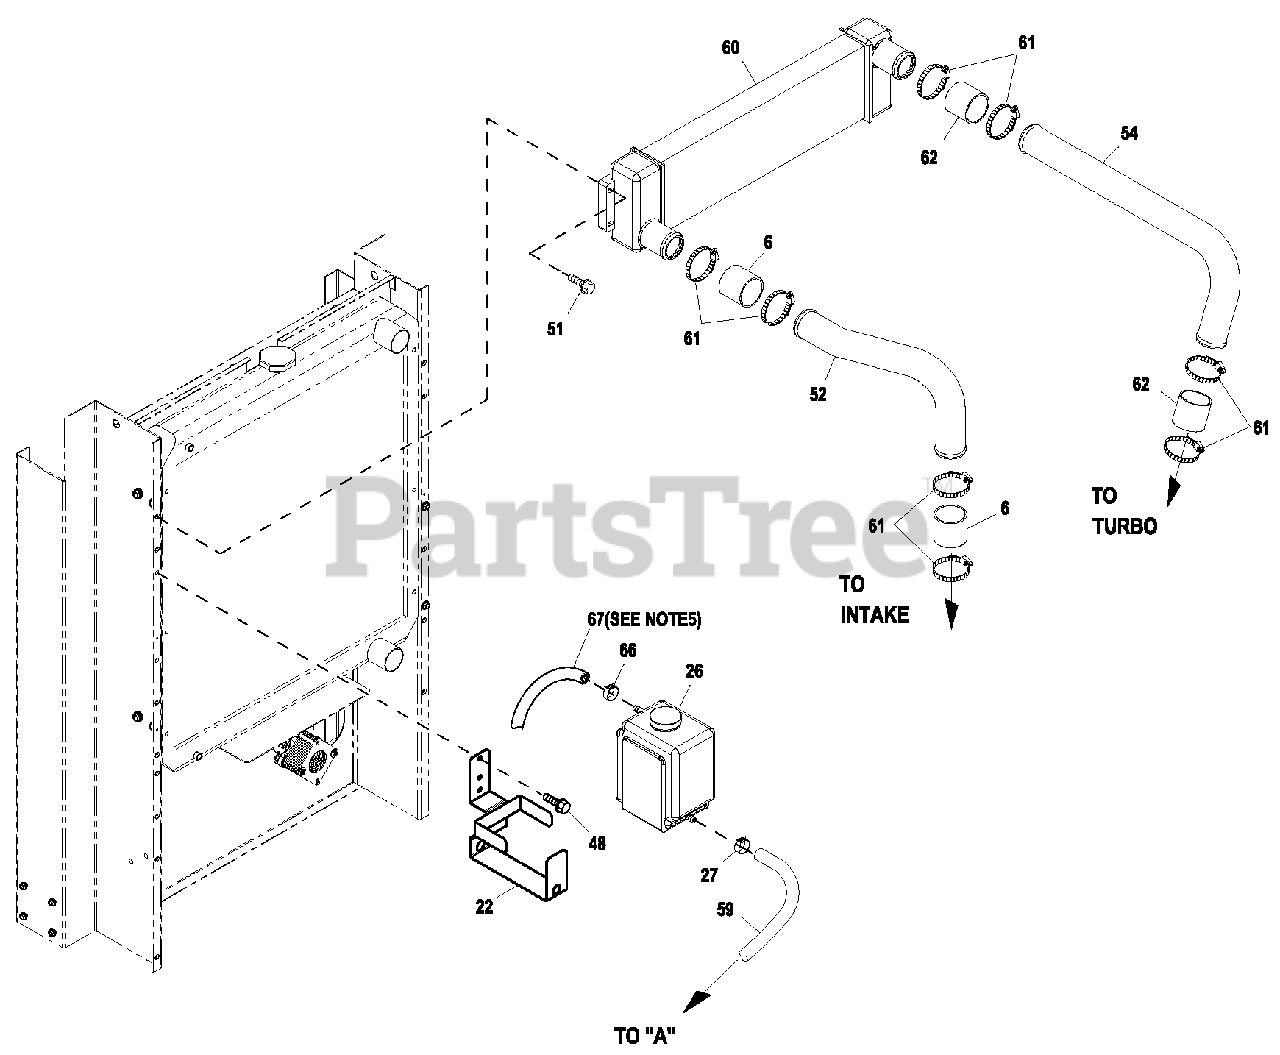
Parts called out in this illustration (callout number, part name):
1	ENGINE 2.4L G2 CERTIFIED
9	WASHER NYLON .565
10	ADAPTER M14-1.50 X 3/8 NPT
11	BARBED EL 90 3/8 NPT X 3/8
12	CLAMP HOSE .38-.87
13	HOSE DRAIN ASSY 28"
14	WASHER FLAT .531 ID X 1.062 OD
15	SCREW HHC M12-1.25 X 20 G10.9
16	SCREW HHC M10-1.25 X 45 G8.8
17	WASHER SHAKEPROOF EXT 7/16 STL
18	SCREW HHC M10-1.25 X 30 G8.8
19	SCREW SHC M8-1.25 X 30 G12.9
20	WASHER LOCK M8-5/16
21	CLAMP HOSE #6 .43-.78
22	TEMPERATU RE SENDER
25	N U T HEX M8-1.25 G8 CLEAR ZINC
28	CAP ANTIFREEZE R UBBER 9.5DIA
33	PL U G STD PIPE 1/4 STEEL SQ HD
35	SCREW HHC M8-1.25 X 25 G10.9
46	FLEX PLATE 2 POLE 2.4L G2
47	ASSY MAGPICK U P(3/8-24 MALE)
48	ADAPTER ENGINE 2.4L MACHINE
49	MOTOR STARTER
52	MANIFOLD INTAKE (MACHINED)
53	GASKET INTAKE MANIFOLD
54	SPACER 2.4L G2 FLEX PLATE
70	CONDUIT FLEX .25"ID
